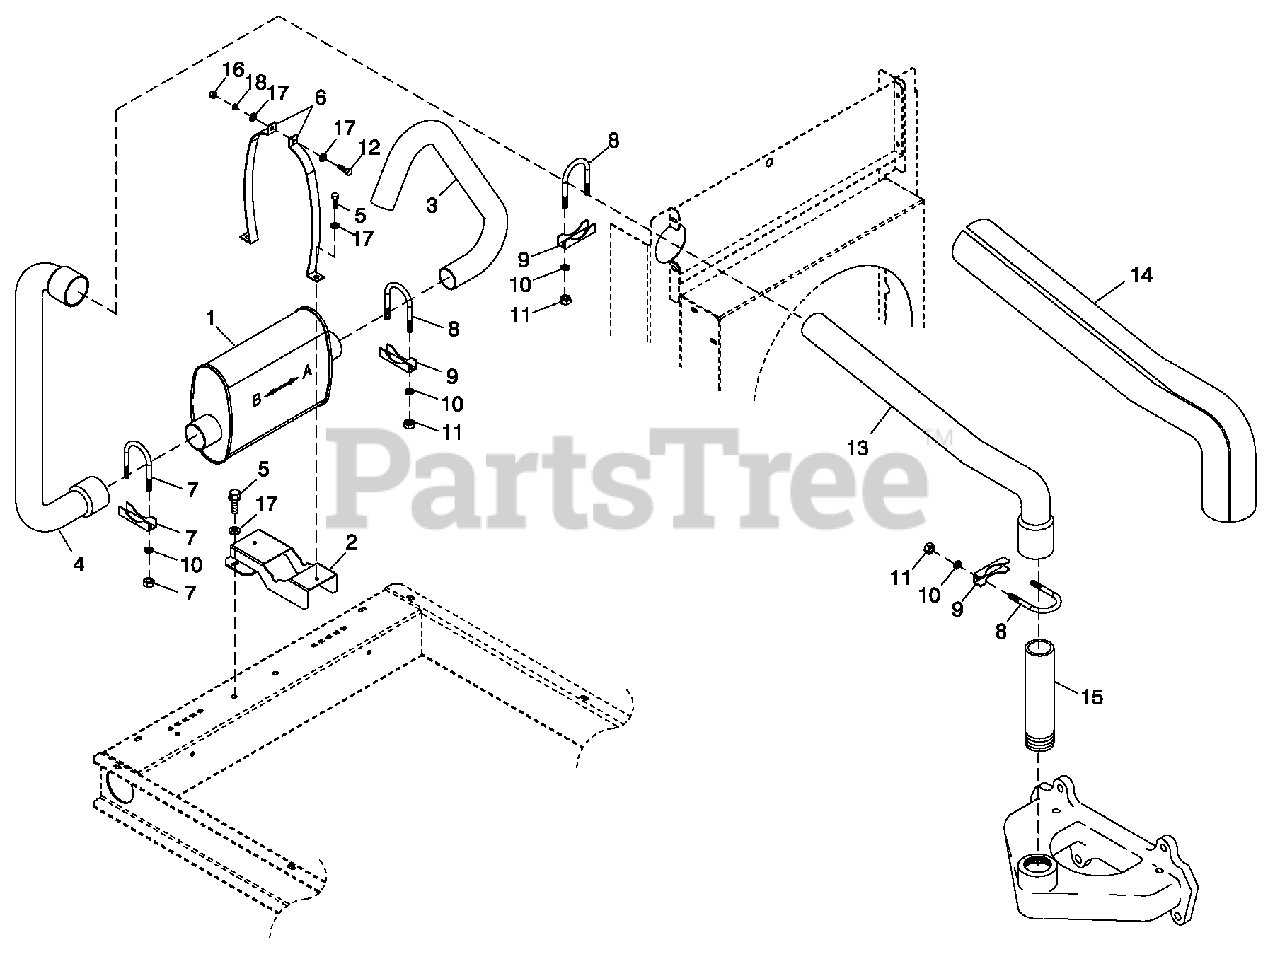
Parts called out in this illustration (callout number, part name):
1	MUFFLER C1
2	MUFFLER SADDLE
3	PIPE EXHAUST OUTLET
4	PIPE EXH INLET MUFLR SIDE 1.5L
5	SCREW HWHTF M6'1.0 X 16
6	MUFFLER STRAP
7	BOLT U 5/16'18 X 2'1/4
8	BOLT U 5/16'18 X 2.09
9	SADDLE 2 INCH
10	WASHER LOCK M8'5/16
11	NUT HEX 5/16'18 STEEL
12	SCREW HHC M6'1.0 X 30 G8.8
13	PIPE EX INLET MANIFLD SIDE 1.5
14	EXHAUST BLANKET 800MM
15	NIPPLE TOE 1.5NPTX5.5 BLK IRON
16	NUT HEX M6 X 1.0 G8 YEL CHR
17	WASHER FLAT 1/4'M6 ZINC
18	WASHER LOCK M6'1/4
